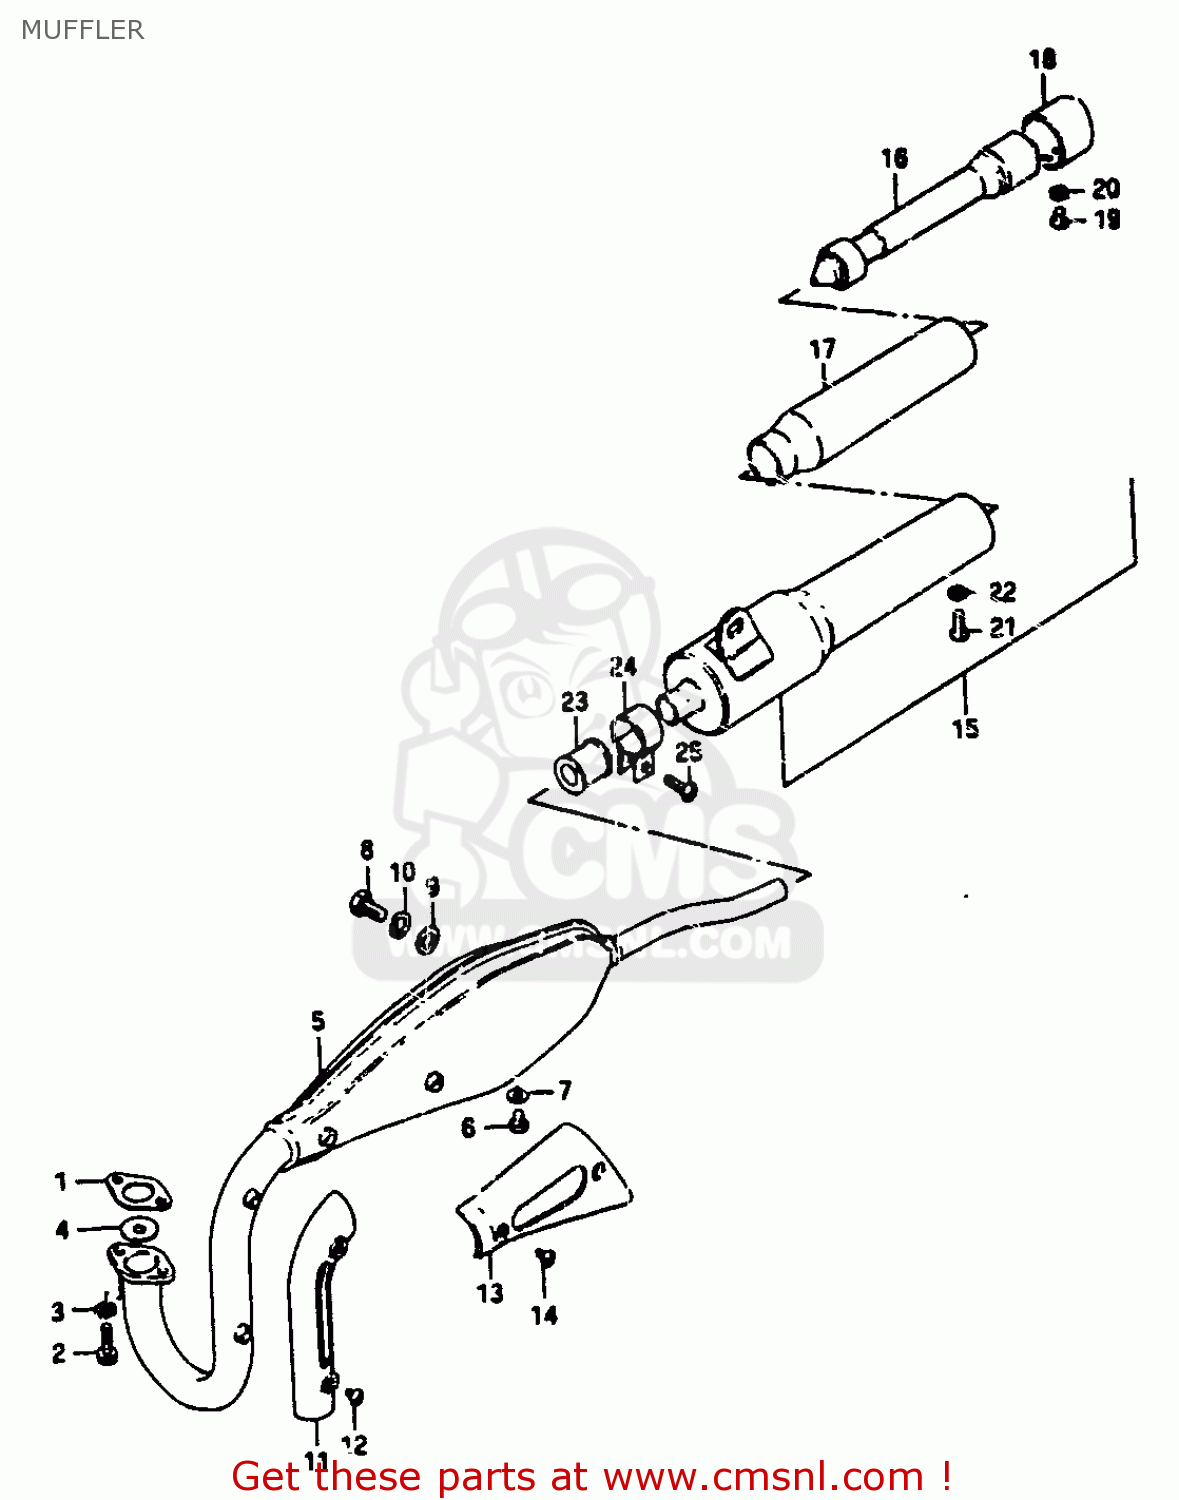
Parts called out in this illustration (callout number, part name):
1	GASKET,EXHAUST PIPE
2	BOLT
3	LOCK WASHER
4	PLATE,EXHAUST PIPE
5	MUFFLER ASSY
6	BOLT
7	WASHER
8	BOLT,8X16
9	WASHER (8.2X20X1.6)
10	LOCK WASHER
11	COVER,EXHAUST PIPE
12	SCREW
13	COVER,MUFFLER
14	SCREW
15	MUFFLER ASSY,2ND
16	TUBE,CLEAN OUT
17	SHELL,ARRESTER
18	CUTTER,MUFFLER TAIL
19	SCREW
20	LOCK WASHER
21	SCREW
22	LOCK WASHER
23	CONNECTOR,MUFFLER
24	CLAMP
25	SCREW
